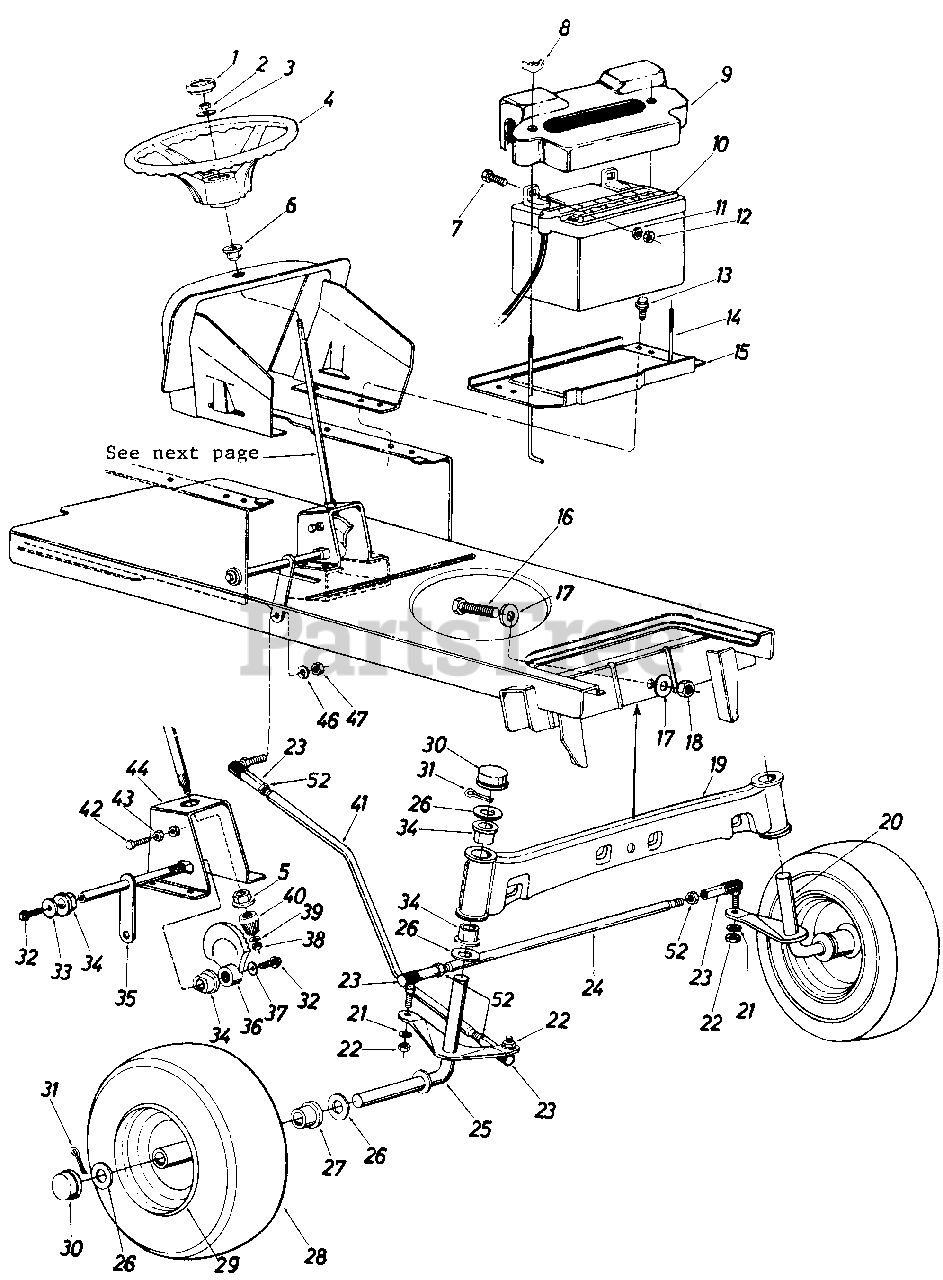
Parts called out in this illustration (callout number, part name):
1	Steering Wheel Cap
2	Hex L-Nut 5/16-24 Thd.
3	Bell-Wash. 5116" I.D. x .87" O.D. x .060
4	Steering Wheel
5	Plastic Hex Bearing 518" 1. D.
6	Steering Column Brg. .890" 1. D.
7	Hex Scr. '/4-20 x .62" Lg.
8	Wing Nut Plastic '/4-20 Thd.
9	Battery Cover
10	32-V Battery
11	L-Wash. 1/4" Scr.
12	Hex Nut 1/4-20 Thd.
13	Hex Thd. Rolling Scr. 1/4-20 x.50" Lg.
14	Battery Hold Down Rod
15	Battery Plate
16	Hex Scr. 5/8-18 x 2.50" Lg.
17	Flat Wash. .66" I.D. x 2.25" O.D. x .17
18	Hex Cent. L-Nut 5/8-18 Thd.
19	Front Pivot Bar Ass'y.
20	Front Axle Ass'y. L.H.
21	L-Wash. 3/8" Scr.
22	Hex Nut 3/8-24 Thd.
23	Ball Joint Ass'y.
24	Tie Rod
25	Front Axle Ass'y. R.H.
26	Fl-Wash. .780 I.D. x 1.59 O.D.
27	Flange Bearing
28	Front Wheel Ass'y. Comp.
28	Front Wheel Tire Only
29	Front Wheel Rim Only
29	Air Valve
29	Grease Fitting
30	Dust Cover
31	Cotter Pin 5132" Dia. x 1.00" Lg.
32	Hex Scr. 3/8-24 x .75" Lg. Grade 5
33	Fl-Wash. 3/8 I.D. x 1.25 O.D. x .090
34	Flange Double "D" Brg. .753 I.D.
35	Steering Arm Shaft Ass'y.
36	Side Gear Steering
37	Bell-Wash. 3/8" I.D.
38	Hex Cent. L-Nut 5/16-24 Thd.
39	Fl-Wash. 5/16" I.D. x .62 0 O.D. x .059
40	Pinion Gear Steering
41	Drag Link
42	Hex Nylon Scr. 3/8-16 x 1.25" Lg.
43	Hex Nut 3/8-16 Thd.
44	Steering Gear Sup. Ass'y.
44	Steering Shaft
46	L-Wash. 3/8" I.D.
47	Hex Nut 3/8-24 Thd.
52	Hex Jam Nut 3/8-24 Thd.
